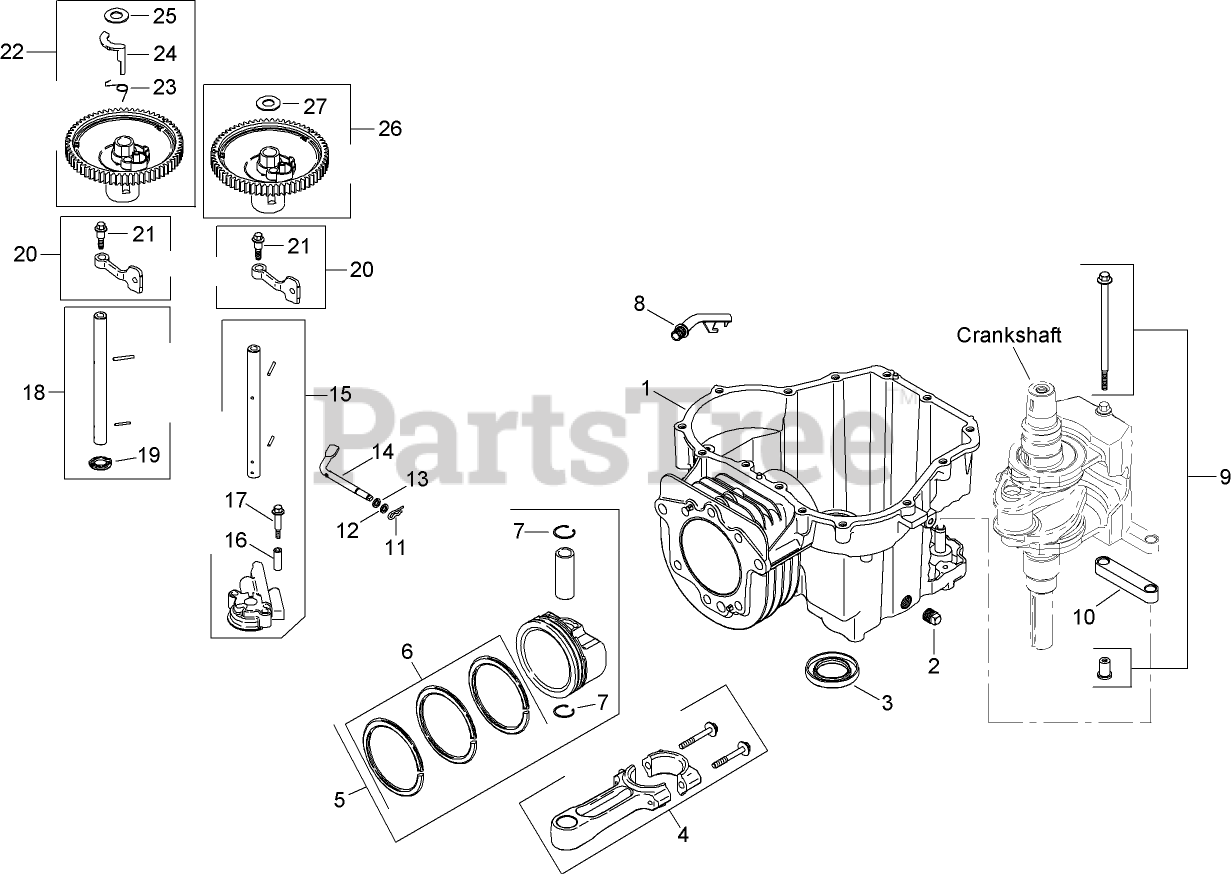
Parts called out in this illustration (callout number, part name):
1	CRANKCASE (SV590/600 SHORT BLOCK)
2	PLUG-PIPE, SQ HD (3/8)
3	Seal-Oil
4	Connecting Rod ASM
5	Piston w/Ring Set (94 mm) (Includes 6-7)
6	Ring Set (94 mm)
7	Retainer-Pin, Piston
8	Tube-Back, Drain
9	LOCATING PIN ASM
10	LINKAGE-WEIGHT, BALANCE
11	Clip-Pin, Hitch
12	WASHER-FLAT (6mm)
13	WASHER-FLAT (1/4)
14	Shaft-Cross, Governor
15	Oil Pump ASM (Includes 17-18)
16	Spacer-Screw, Oil Pump
17	Screw-Pump, Oil
18	CAMSHAFT CENTER ASM (EXHAUST) (INCLUDES REF 19)
19	WASHER-THRUST
20	Cam Lever ASM (Includes 22)
21	Bolt-Shoulder (M6x1x26)
22	Cam Gear ASM - Intake (Includes 28)
23	Spring-A C R
24	Weight-A C R
25	Washer-Thrust, A C R
26	Cam Gear ASM - Intake (Includes 28)
27	Washer-Thrust, A C R
